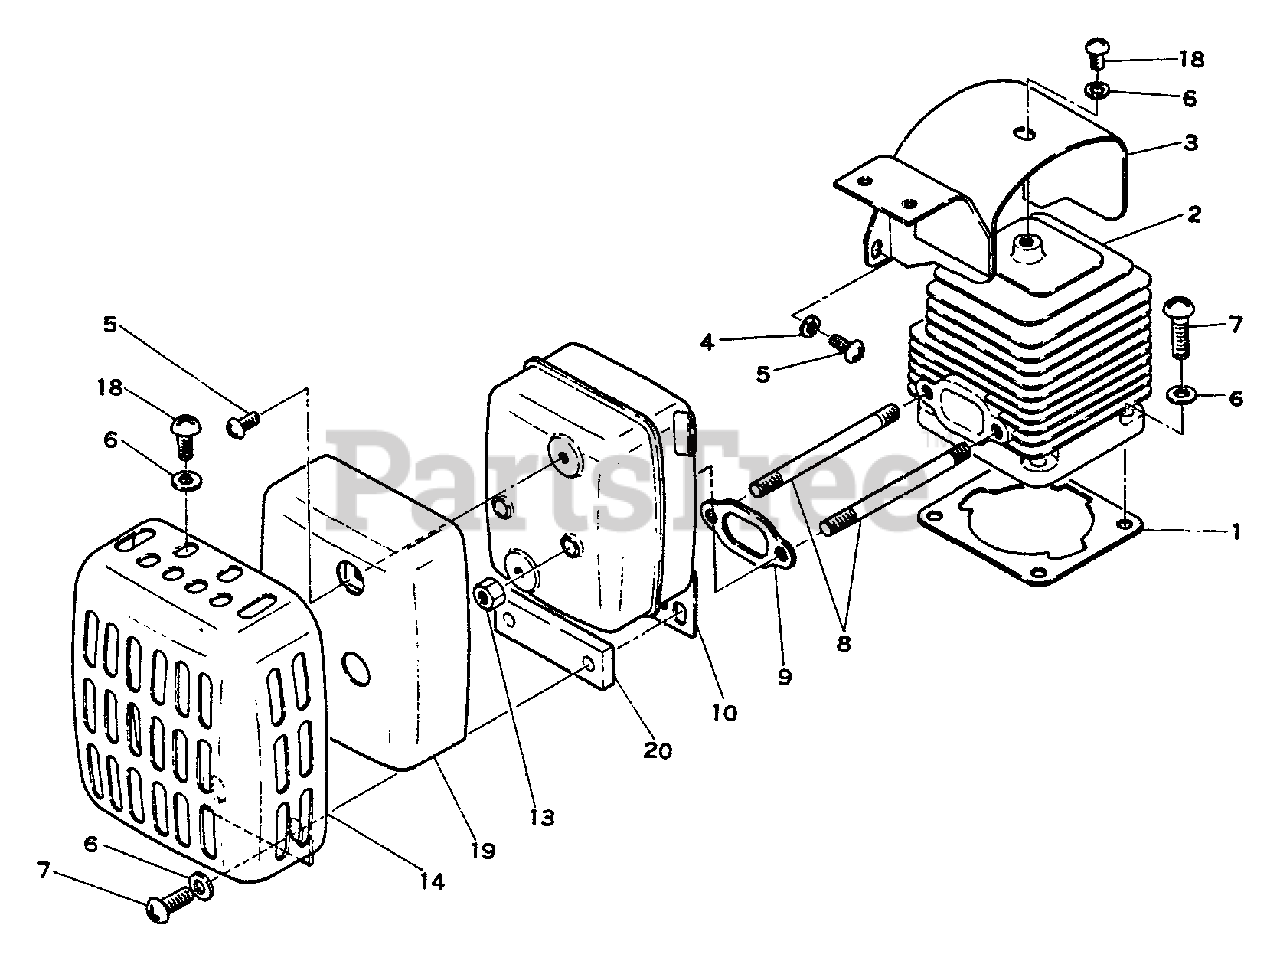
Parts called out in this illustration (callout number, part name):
1	GASKET, CYLINDER
2	CYLINDER
3	SHIELD, CYLINDER
4	WASHER - 4
5	SCREW - 4X8
6	WASHER - 5
7	SCREW - 5X16
8	STUD
9	GASKET, EXHAUST
10	MUFFLER
13	LOCKNUT - 5
14	COVER, MUFFLER
18	SCREW - 5X10
19	INSULATOR
20	SPACER
